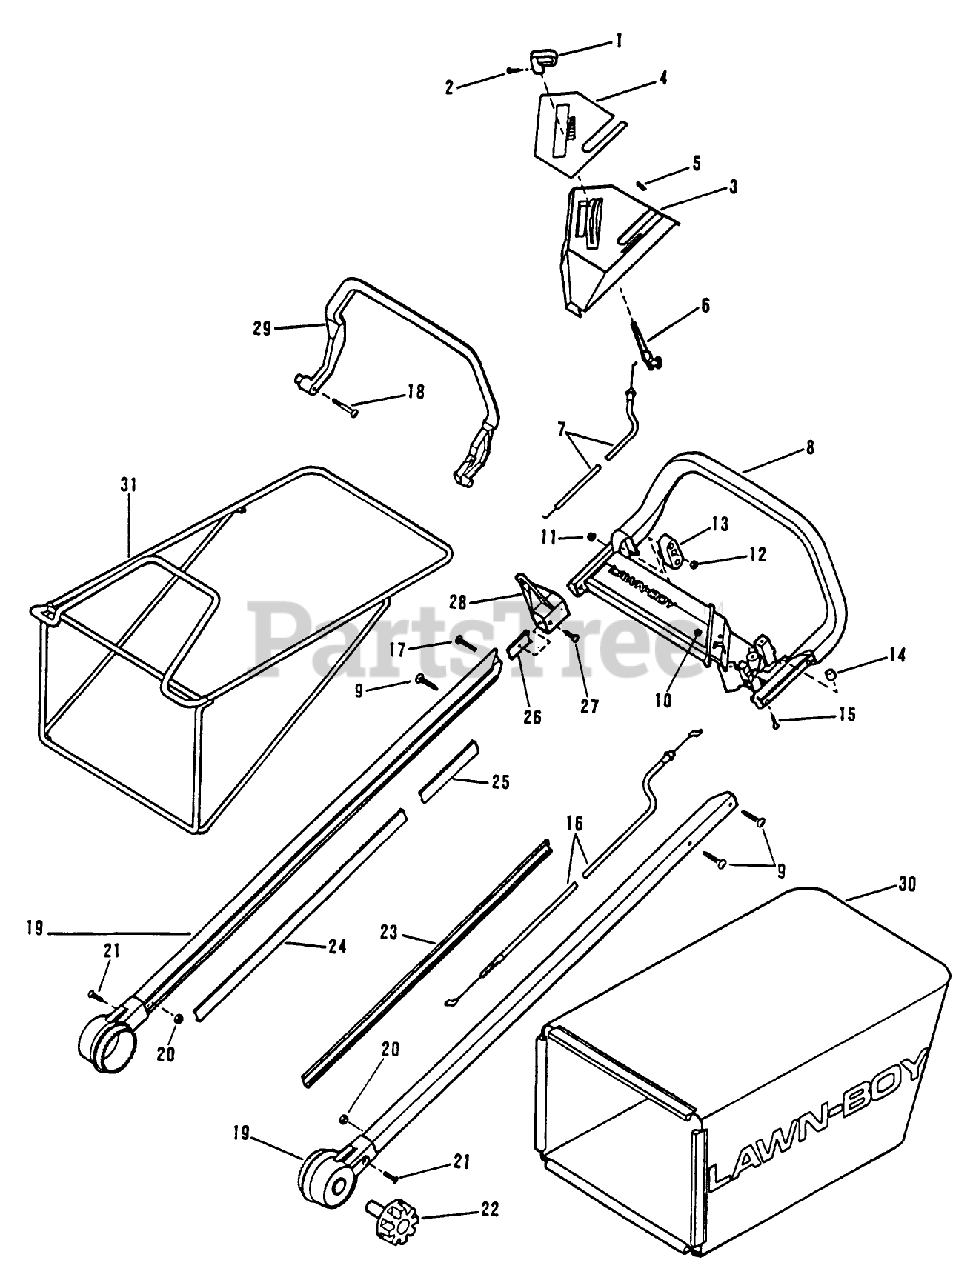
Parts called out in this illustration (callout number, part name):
11	LOCKNUT FLAN
12	LOCKNUT E
13	BLOCK BAIL PL
16	CABLE ASSEMBLY
17	SCREW-TRUSS
19	HANDLE SHAFT AY
20	LOCKNUT FLAN
22	KNOB-HDLE MT.ASM*B
23	INSERT - HANDLE
